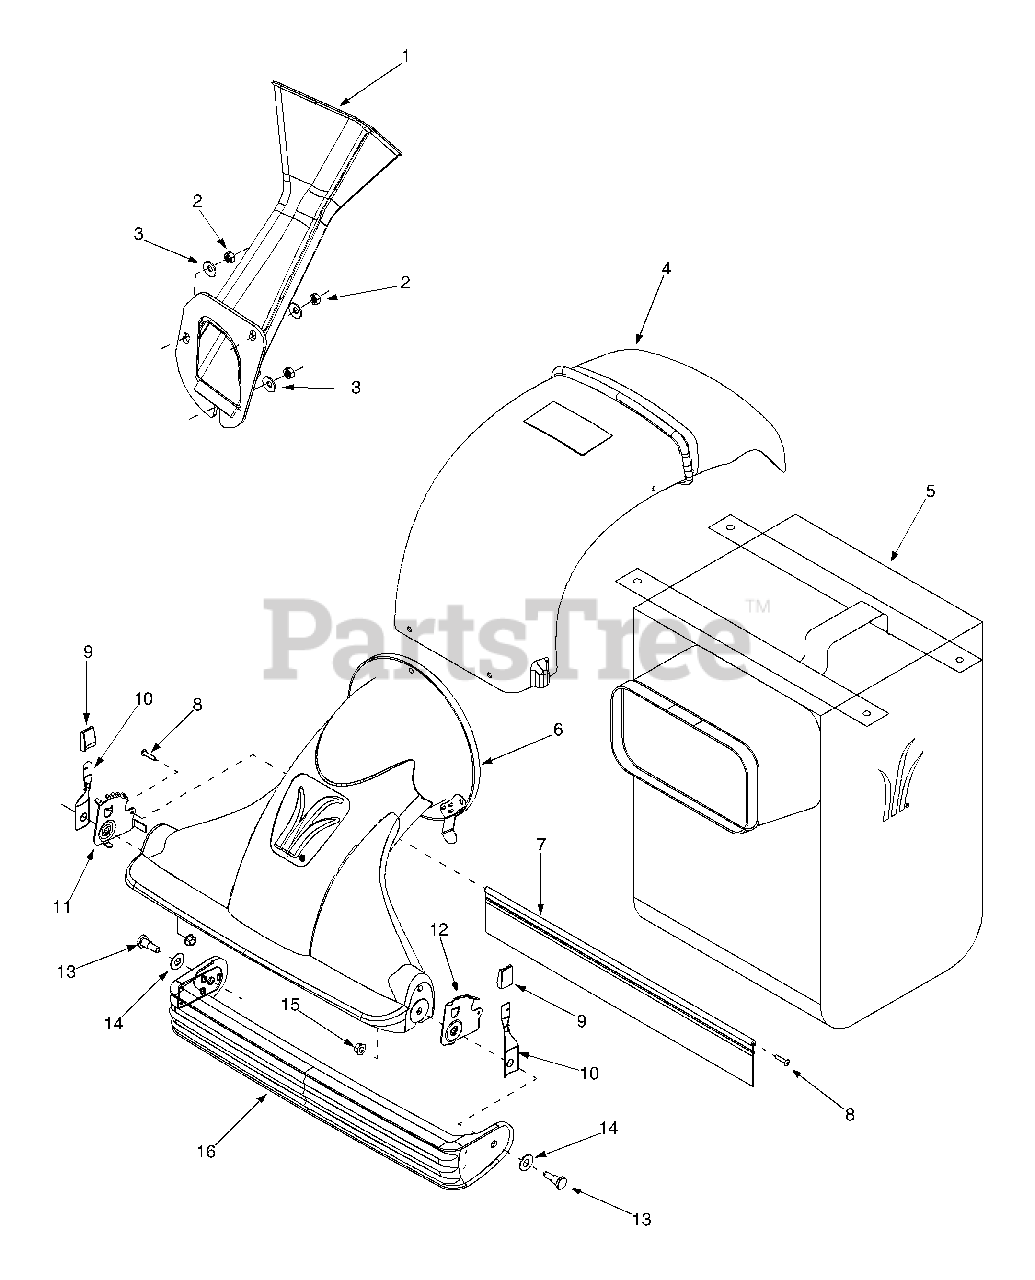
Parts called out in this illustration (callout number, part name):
2	Hex Nut 5/16-18
3	Bell Washer .340 ID x .872 OD
4	Discharge Chute
5	Bag
6	Nozzle Assembly
7	Nozzle Flap
8	Screw
9	Height Adjustment Knob
10	Spring Lever
13	Shoulder Screw
14	Flat Washer .510 x 1.12 x .060
15	Hex Flange Lock Nut 3/8-16
16	Door Assembly
